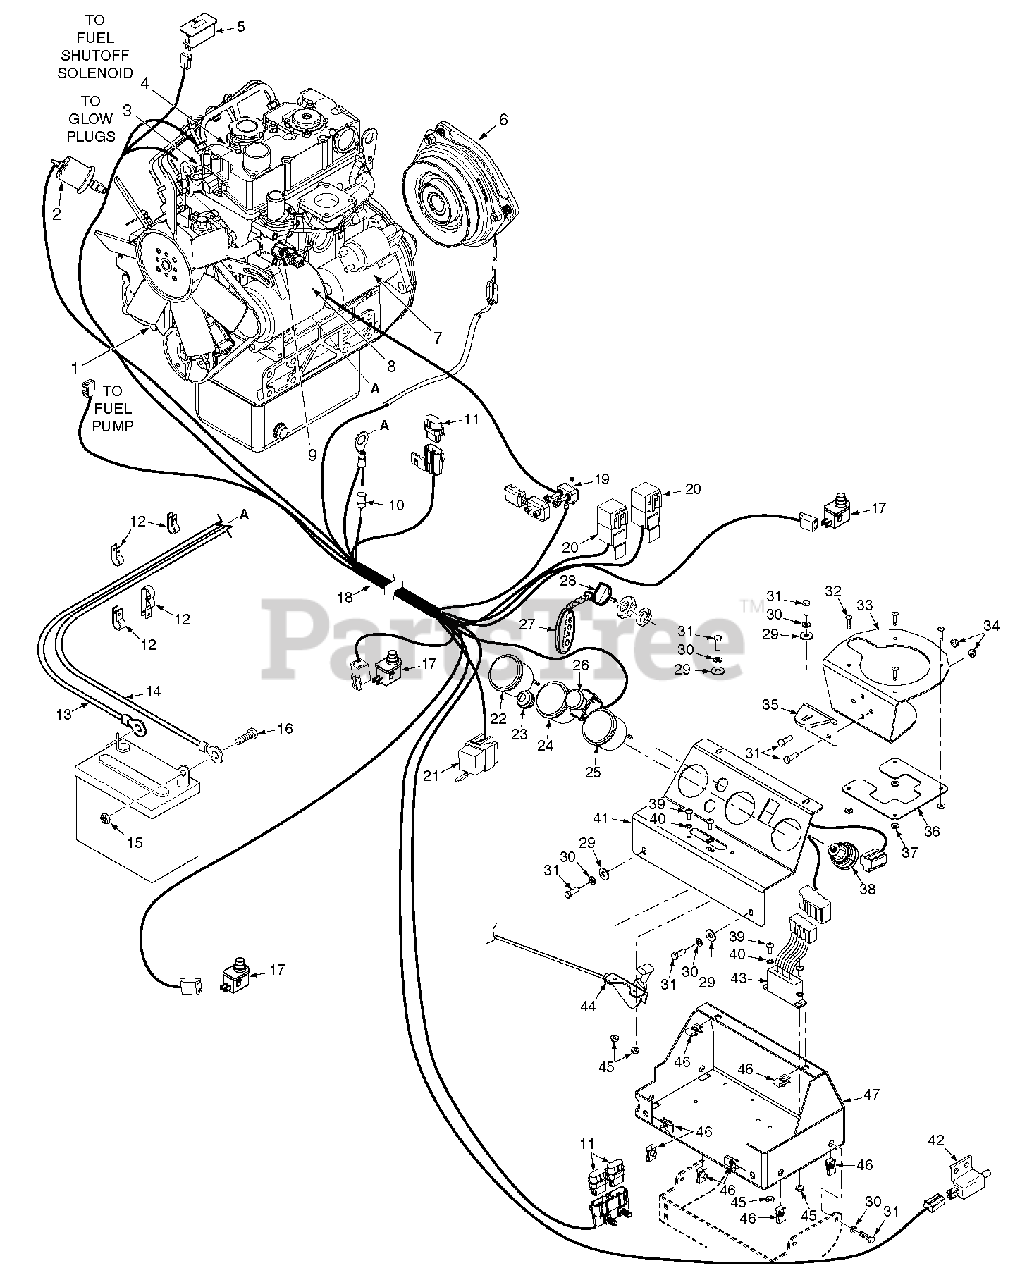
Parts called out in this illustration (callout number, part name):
1	Fuel Pump
2	Oil Pressure Sender
3	Glow Plugs
4	Fuel Shutoff Solenoid
5	Hourmeter
6	Clutch, Ogura GT 3.5 - 1.125 Bore
7	Starting Motor
8	Alternator
9	Sending Unit, Water Temp.
10	Diode
11	Fuse, 20 AMP
12	Clamp, Cable 1/2" ID.
12	Clamp, Cable 3/4" ID.
12	Clamp, Double Cable 5/8" ID.
13	Cable, Battery - Red
14	Cable, Battery - Black
15	Nut, Hex 1/4-20
16	Bolt, Hex Head 1/4-20 x .5" Battery, (Not Available Through Scag)
17	Switch, Interlock, Normally Open
18	Main Wire Harness, STT Cat
19	Circuit Breaker, 50 AMP
19	Cover, Circuit Breaker
20	Relay, 12V 40 AMP Hi Capacity
21	Relay, 12V 40 AMP Standard
22	Volt Meter (Includes Mounting Hardware)
23	Indicator Light, Glow Plugs (Includes Mounting Hardware)
24	Engine Oil Pressure Gauge (Includes Mounting Hardware)
25	Water Temperature Gauge (Includes Mounting Hardware)
26	Switch, PTO
27	Key Assembly w/Fob
28	Key, Ignition
29	Flat Washser, 1/4"
30	Lockwasher, 1/4"
31	Bolt, Hex Head 1/4-20 x 3/4"
32	Pop Rivet, 3/16" x 5/8"
33	Cupholder
34	Nut, Elastic Stop 1/4"-20
35	Bracket, Cupholder Mounting
36	Retainer, Cupholder
37	Flatwasher, 0.196 ID.
38	Key Switch (Includes Mounting Hardware)
39	Screw, Phillips Washer Head #10-32 x 1/2"
40	Lockwasher, #10 External Tooth
41	Instrument Panel, Top w/Decals
42	Switch, Interlock, Park Brake Normally Open
43	Electronic Control Module
44	Throttle Control
45	Nut, Hex #10-32
46	U-Nut, 1/4-20
47	Base, Instrument Panel
